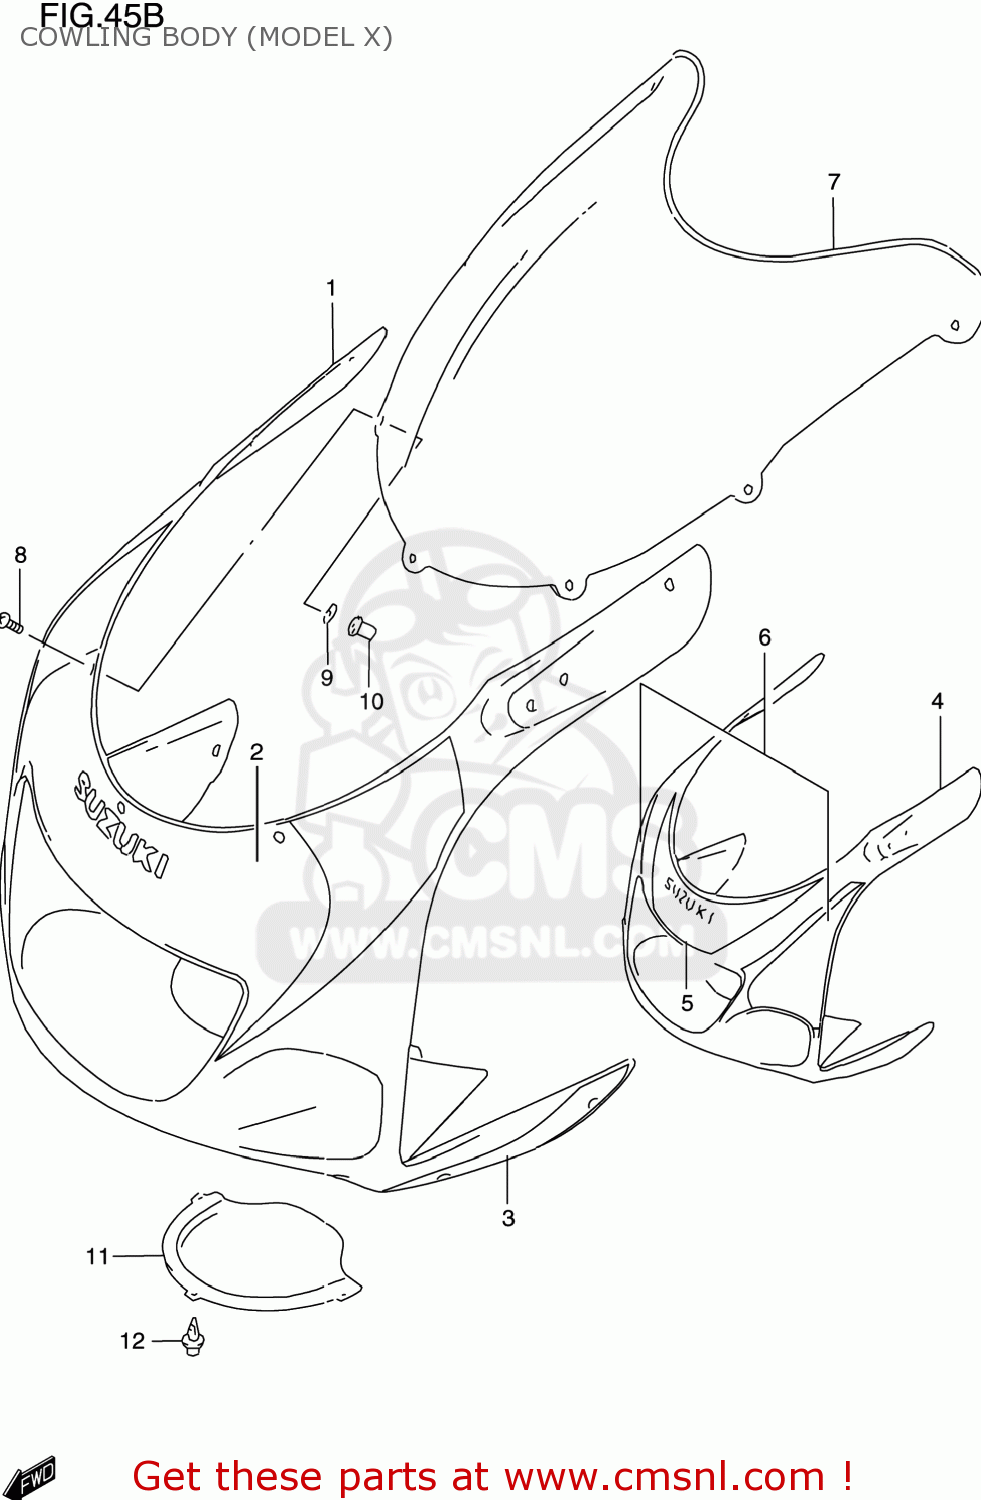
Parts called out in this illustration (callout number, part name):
1	COWLING ASSY,BODY(BLUE)
2	TAPE SET,COWL BODY FR
3	TAPE SET,COWL BODY SIDE
4	COWLING ASSY,BODY(YELLOW)
5	TAPE,COWL BODY FR
6	TAPE SET,COWL BODY SIDE
7	WINDSCREEN
8	SCREW(5X14)
9	WASHER
10	NUT
11	LID,BODY COWL LWR
12	CLIP(BLACK)
